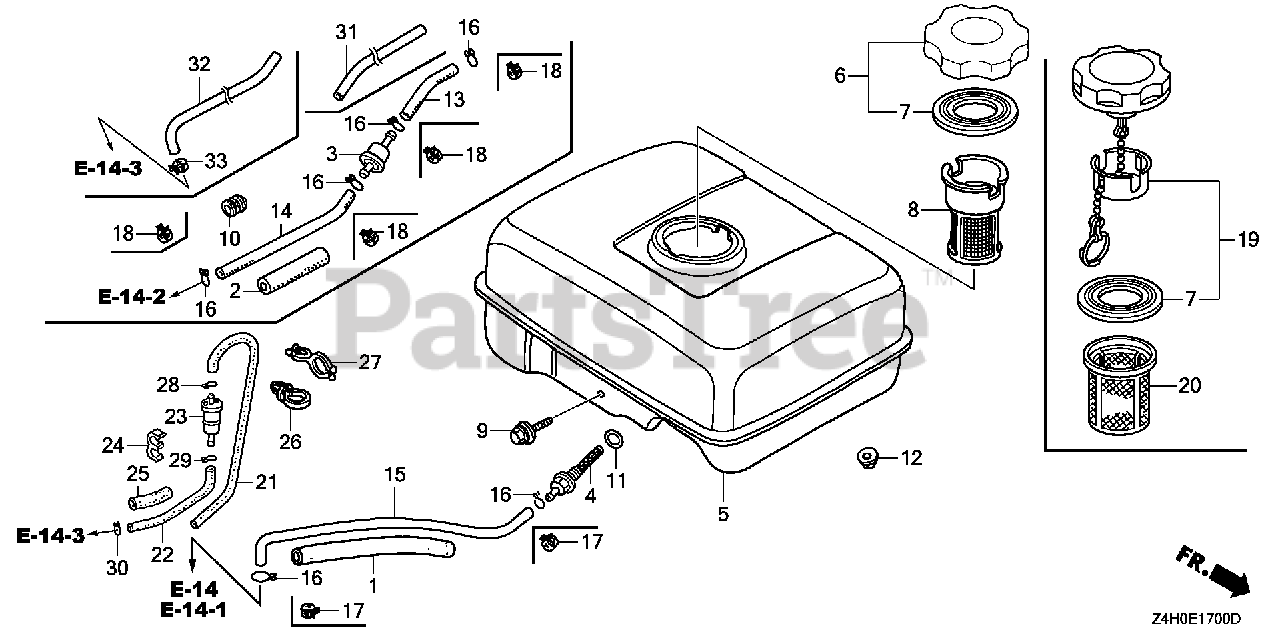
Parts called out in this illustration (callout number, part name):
1	RUBBER, SUPPORTER (107MM)
4	JOINT, FUEL TANK
5	TANK, FUEL *NH31* (MCKINLEY WHITE)
6	CAP, FUEL FILLER (CHROME PLATED)(RADICON)
7	GASKET, FUEL FILLER CAP
7	GASKET, FUEL FILLER CAP (39X62X3)
9	BOLT, FLANGE (6X29)
11	O-RING (14MM) (ARAI) Use up to Engine SN 2949254.
11	O-RING (14MM) (NOK)
12	NUT, FLANGE (6MM)
15	TUBE, FUEL (4.5X140) (FKM)
15	BULK HOSE, FUEL (4.5X3000) (Honda Code 5137104). (4.5X140)
16	CLIP, TUBE (B8)
17	CLIP, TUBE (D8)
19	CAP, FUEL FILLER
19	CAP, FUEL FILLER (CHROME PLATED)
